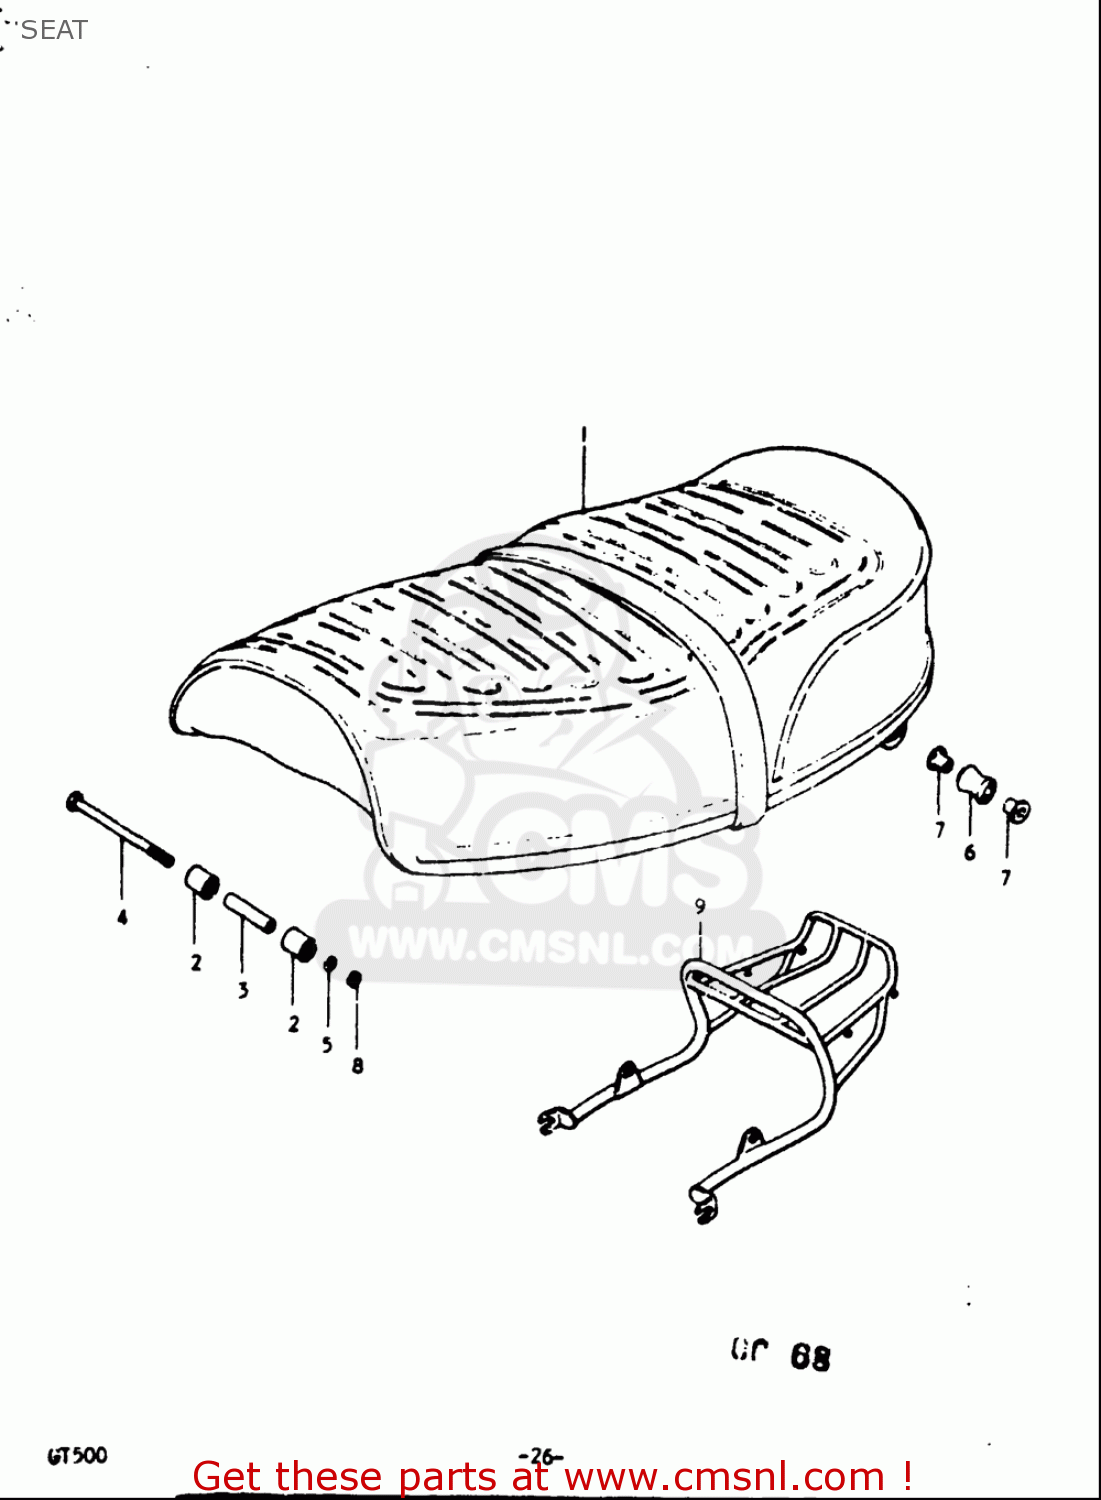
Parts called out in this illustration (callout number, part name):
4	BOLT 8X125
5	WASHER,LOCK
6	BUSH
8	NUT
